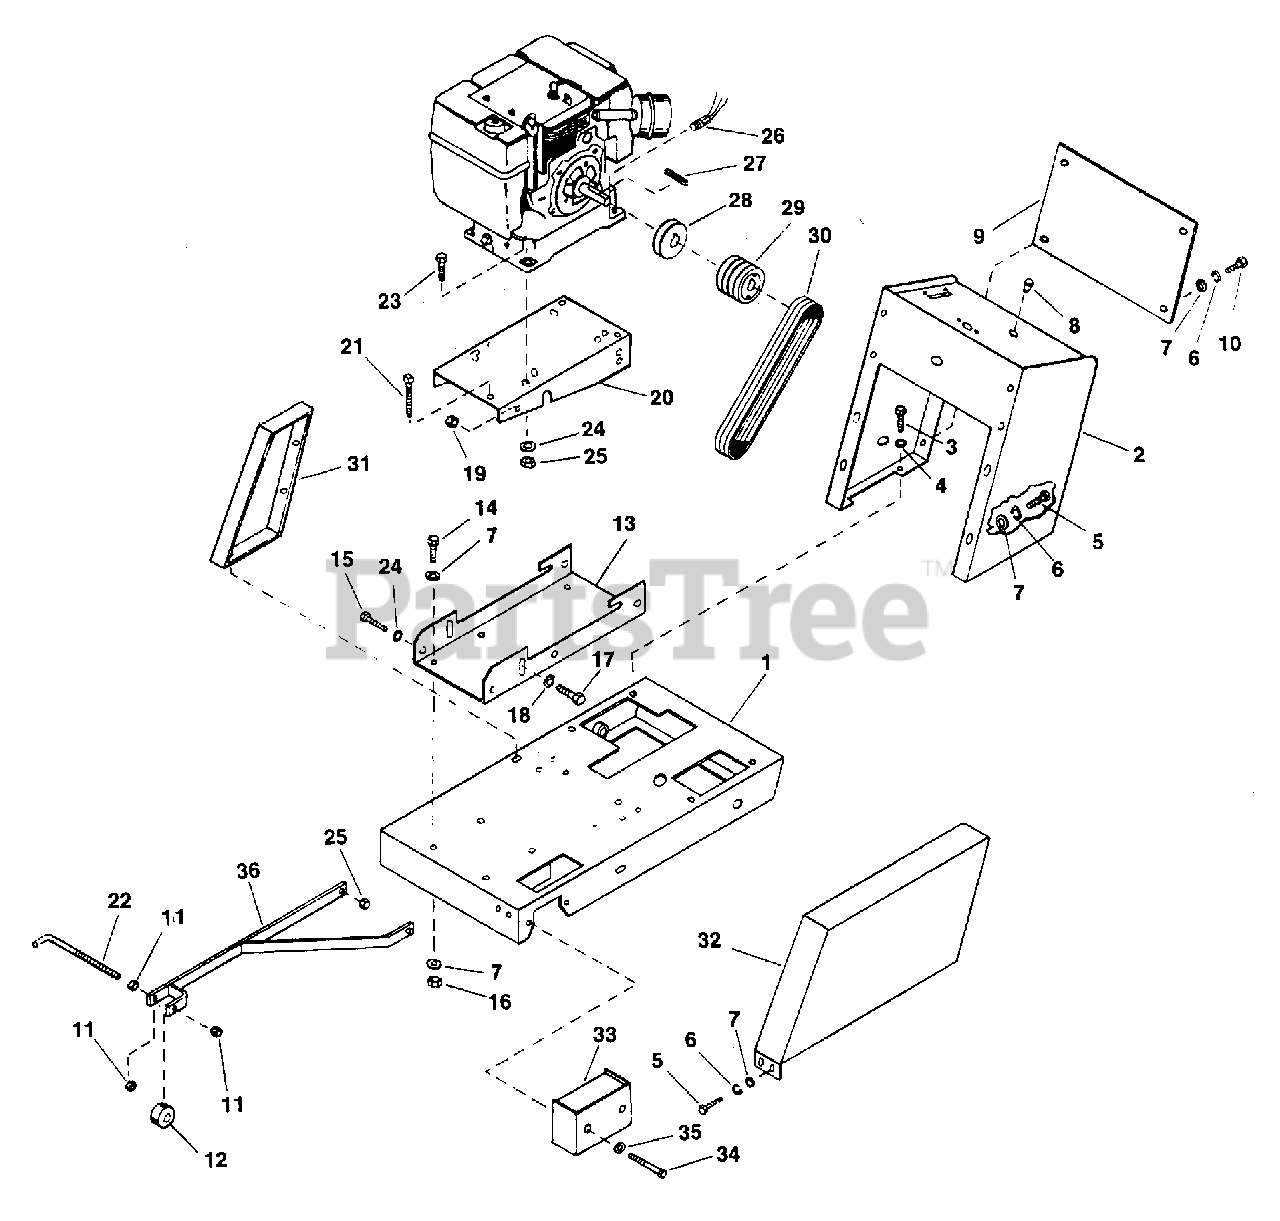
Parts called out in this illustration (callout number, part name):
1	BASE- Frame
2	FRAME- Upright
3	CAPSCREW- Hex Hd., 5/16-18 x 3/4" Grd. 5
4	WASHER- Sae 5/16" Dia.
5	CAPSCREW- Hex Hd. 1/4-20 x 5/8" Grd. 5
6	WASHER- Lock, Split Type 1/4" Dia.
7	WASHER- Sae 1/4" Dia.
8	BUTTON- Kill
9	PLATE- Back Cover
10	CAPSCREW- Hex Hd. 1/4-20 x 5/8" Grd. 5
11	NUT- Hex 3/8-16
12	WHEEL- 2 1/2" Dia.
13	MOUNT- Engine Base
14	CAPSCREW- Hex Hd. 1/4-20 x 1" Grd. 5
15	CAPSCREW- Hex Hd. 3/8-16 x 1" Grd. 5
16	LOCKNUT- Fiber Type 1/4-20
17	CAPSCREW- Hex Hd. 1/2-13 x 1 1/4" Grd. 5
18	WASHER- Sae 1/2" Dia.
19	LOCKNUT- Fiber Type 1/2-13
20	BASE- Engine
21	SETSCREW- 1/2-13 x 4" lg.
22	ROD- Pointer
23	CAPSCREW- Hex Hd. 3/8-16 x 1 1/2" for 8HP, 12HP, 14HP and 16HP
24	WASHER- Sae 3/8" Dia.
25	LOCKNUT- Fiber Type, 3/8-16
26	OIL SENTRY PROTECTER
27	KEY- 1/4 x 21/2"
28	PULLEY-Accessory on Engine, 4L Groove 2.70" O.D.x1 1/8" Bore/w Setsc
29	PULLEY-Engine
30	BELT-375 3V, matched set of 3 for 12,14,16HP Gas & 5, 71/2 HP Electric
31	GUARD- Small Side
32	GUARD- Belt
33	GUARD- Shaft Weldment
34	CAPSCREW- Hex Hd. 5/16-18 x 31/4" Grd. 5
35	WASHER- Lock, Split Type 5/16" Dia.
36	POINTER ASSEMBLY
